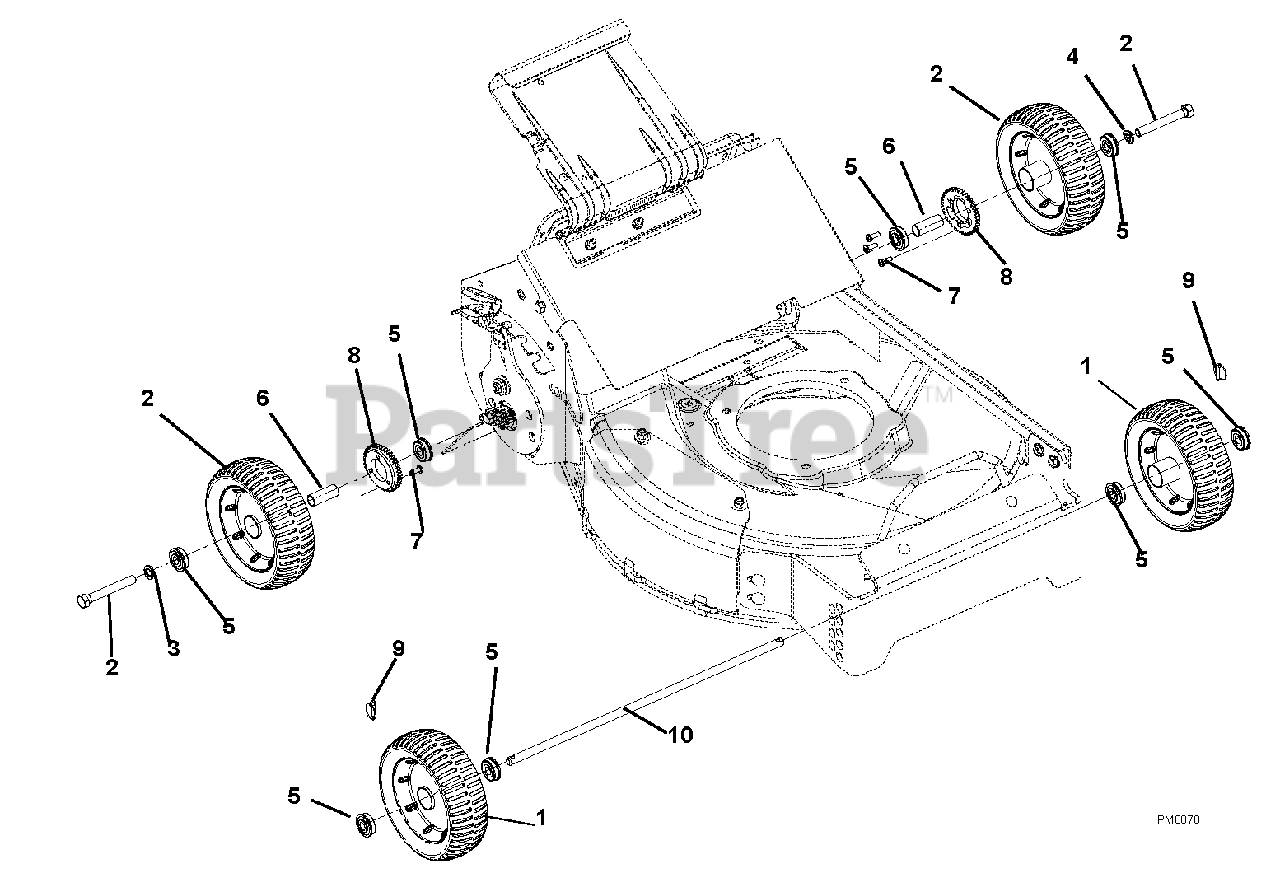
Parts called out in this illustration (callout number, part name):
1	Wheel Assembly, 8.25 x 2.75 Front (Includes item 5)
2	Wheel Assembly, 8.25 x 2.75 Rear (Includes items 5 and 6)
3	Bolt, Hex .50-13 x 3.75 Grade 5
4	Washer, Locking .50 x .125 Regular
5	Bearing, Ball .50 x 1.38 x .437
6	Spacer, Wheel
7	Screw, Tapping 1/4-20 x 3/4
8	Gear, Wheel
9	Pin, Klik 1.000 x .188 x 1.25
10	Axle Shaft
